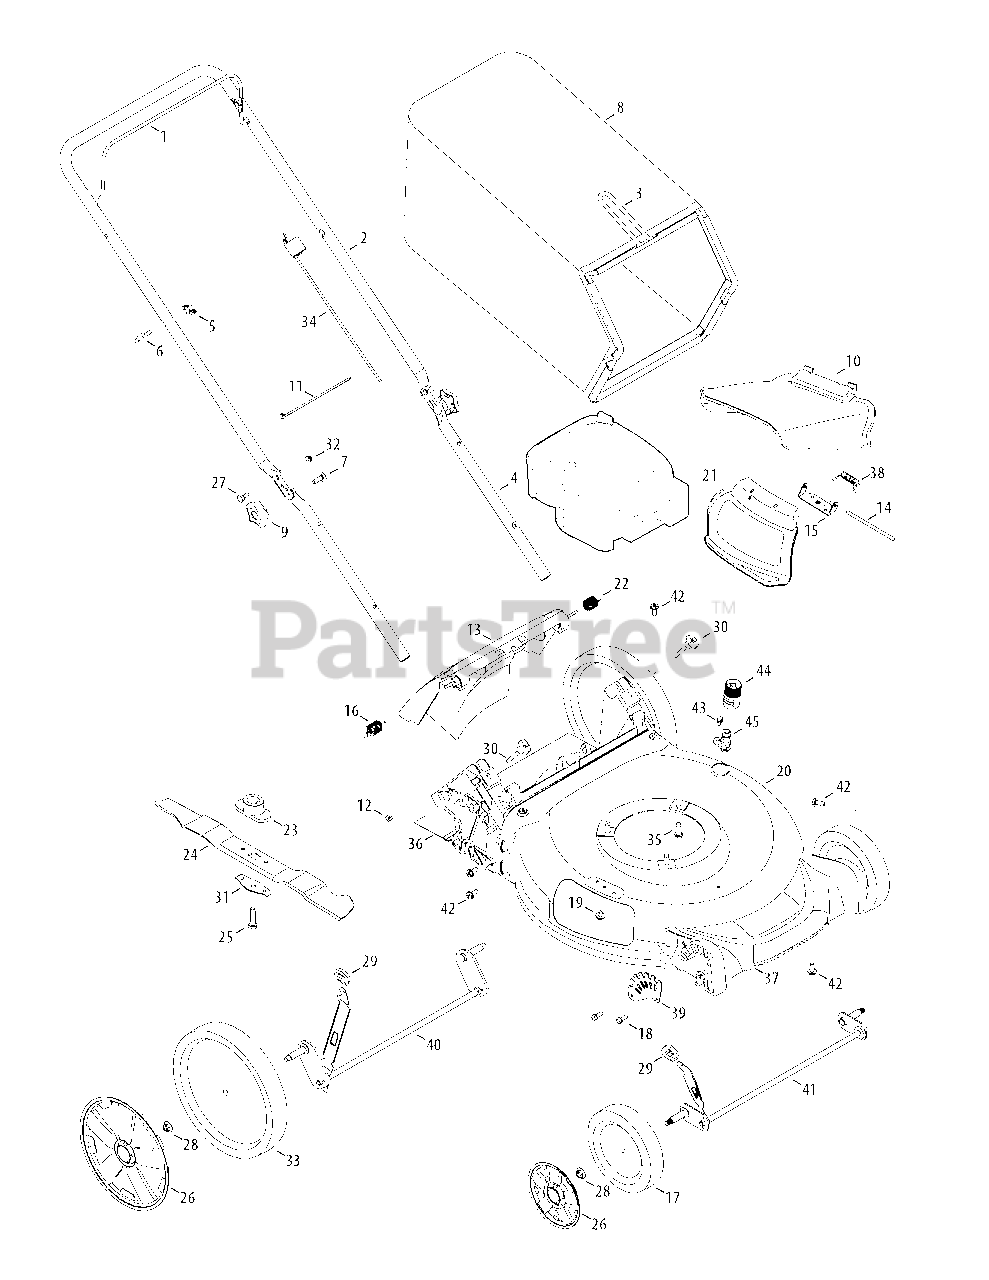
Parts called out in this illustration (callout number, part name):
1	Blade Control
2	Upper Handle
4	Lower Handle
5	Wing Nut
6	Rope Guide
7	Carriage Screw ,5/16-18
8	Grass Bag
9	Hand Knob
10	Side Chute
11	Cable Tie
12	Nut, Sq., 1/4-20
13	Rear Discharge Door Assembly
14	Hinge Pin
15	Chute Deflector Bracket
16	Torsion Spring - RH
17	Wheel, 7 x 2
18	Screw, 1/4-15 x .750
19	Screw, 1/4-20 x .500
20	Deck - 21"
21	Hinged Mulch Plug Assembly
22	Torsion Spring - LH
23	Blade Adapter
24	Mulching Blade
25	Screw , 3/8-24 x 1.50
26	Hub Cap - Front
26	Hub Cap - Rear
27	Sldr. Screw, .375 x .126 x 1/4-20
28	Flange Lock Nut, 3/8-16
29	Adjustment Lever Knob
30	Wing Knob
31	Blade Bell Support
32	Nut, Flange Lock, 1/4-20
33	Wheel, 11 x 2
34	Control Cable
35	TT Screw, 3/8-16 x 1.0
36	Trail shield
37	Front Cover
38	Torsion Spring
39	Front Height Adjuster Plate
40	Rear Axle Assembly
41	Front Axle Assembly
42	Screw, 5/16-14 x .750
43	Shldr. Screw, 1/4-20 x .50
44	Water Nozzle Adapter
45	Deck Wash Nozzle
